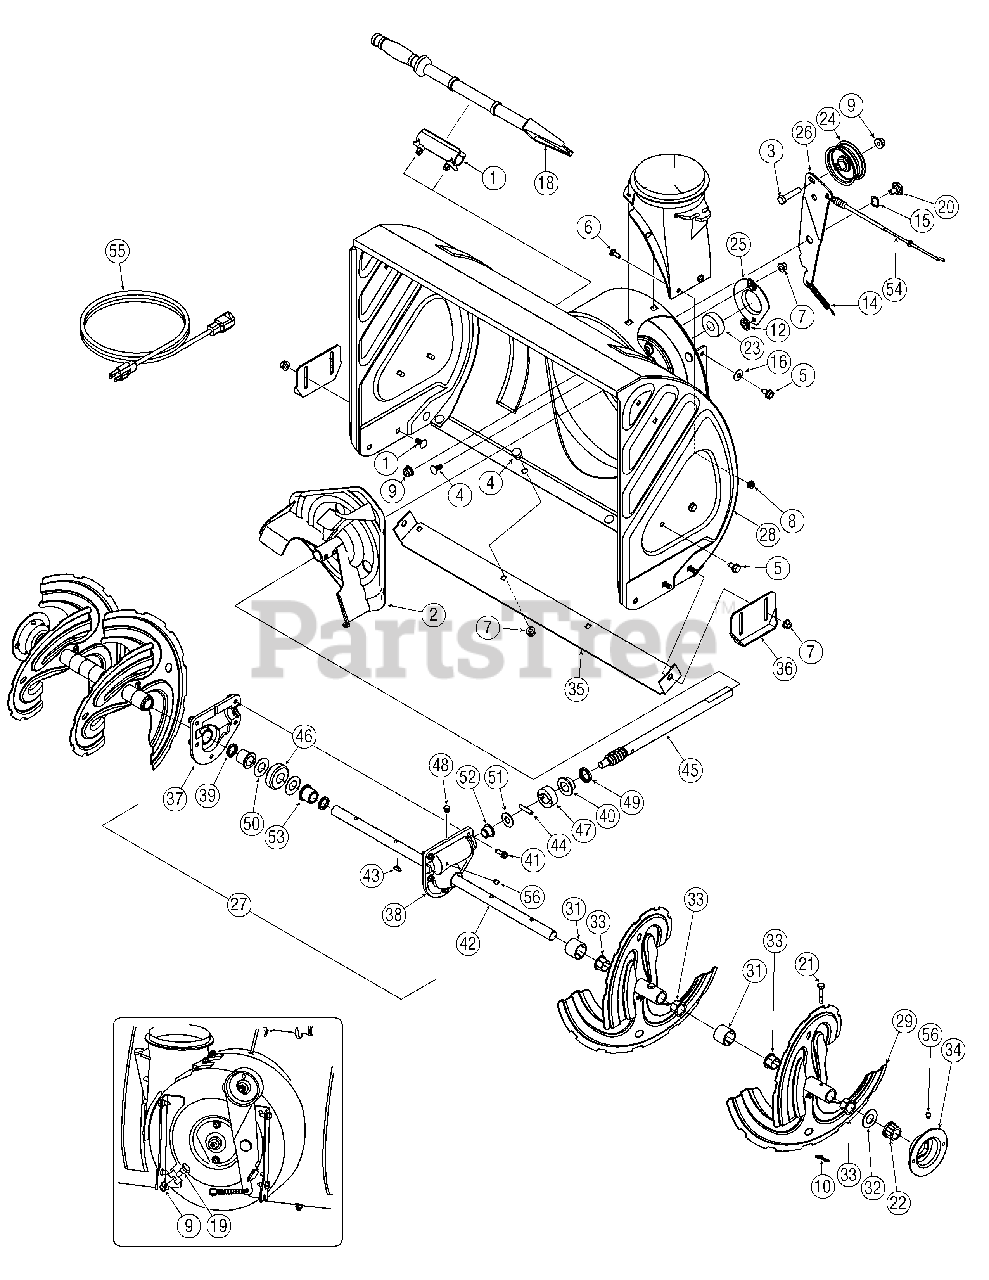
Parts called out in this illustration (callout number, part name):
1	Snow Removal Tool Mount
3	Hex Screw, 3/8-16, 1.75, Gr5
4	Bolt, Carriage, 5/16-18, .750
5	Screw, 5/16-18, 0.625
6	Screw, Carriage, 1/4-20, .750,
7	Nut, Flange Lock, 5/16-18,
8	Nut, Flange Lock, 1/4-20,
9	Nut, Flange Lock, 3/8-16,
10	Cotter Pin, Bow-tie
11	Cable, Tie, 3/16 x .05 x 7
12	Nut, Push-on, .25 Dia
13	Chute, Adapter 5" Dia
14	Spring, Extension, .38 OD x
15	Washer, Wave, .625 x .885
16	Washer, Bell, .340 x .872 x
17	Washer, Flat, .25 x .630 x
18	Snow Removal Tool
19	Screw, Shoulder, .498 x .34,
20	Screw, Shoulder, .625 x .17,
21	Shear Pin, .25 x 1.50
22	Bearing, Hex Flange x .75
23	Bearing, Ball, .75 ID x 1.85
24	Flat Pulley, Idler, 2.75 OD
25	Housing, Bearing, 1.85 ID
27	Gearbox Assembly, Auger, 24"
28	Housing Ass’y, Troy-Bilt, Auger
31	Spacer, 1.25 OD x .75 ID x 1.00
32	Washer, Flat, .76 x 1.49 x .06
33	Bushing, Flange, .80 ID x .91 OD
36	Screw, Carriage 5/16-18 x .750
36	Nut, Nylon Lock 5/16-18
36	Washer, Flat .349 x .879 x .063
36	Skid Shoe, Polymer Small
36	Standard Polymer Reversible Shoe Kit
36	Screw, Carriage 5/16-18 x 1.00
37	Housing, Auger, RH Reduced
38	Housing, Auger, LH Reduced
39	Seal, Oil, .750 ID
40	Bearing, Flange, .75 x 1.0 x .59
41	Screw, Self-tapping, 1/4-20, 0.750
42	Axle, Auger, 24"
43	Key, Hi-pro 3/16 x 5/8
44	Pin, Dowel, .25 OD x 1.2
45	Shaft, Worm .75 OD
46	Gear, Worm 20T
47	Collar, Thrust
48	Plug, 1/4 x .437
49	Seal, Oil, .75 x 1 x .131
50	Washer, Flat, .760 ID x 1.5 OD
51	Washer, Flat, .51 x 1.12
52	Bearing, Flange, .75 x 1.0 x .925
53	Bearing, Flange, .75 x 1.00 x .975
54	Clutch Cable, Auger, 47.23"
55	Extention Cord, 110V
56	Grease Fitting, 3/16"
